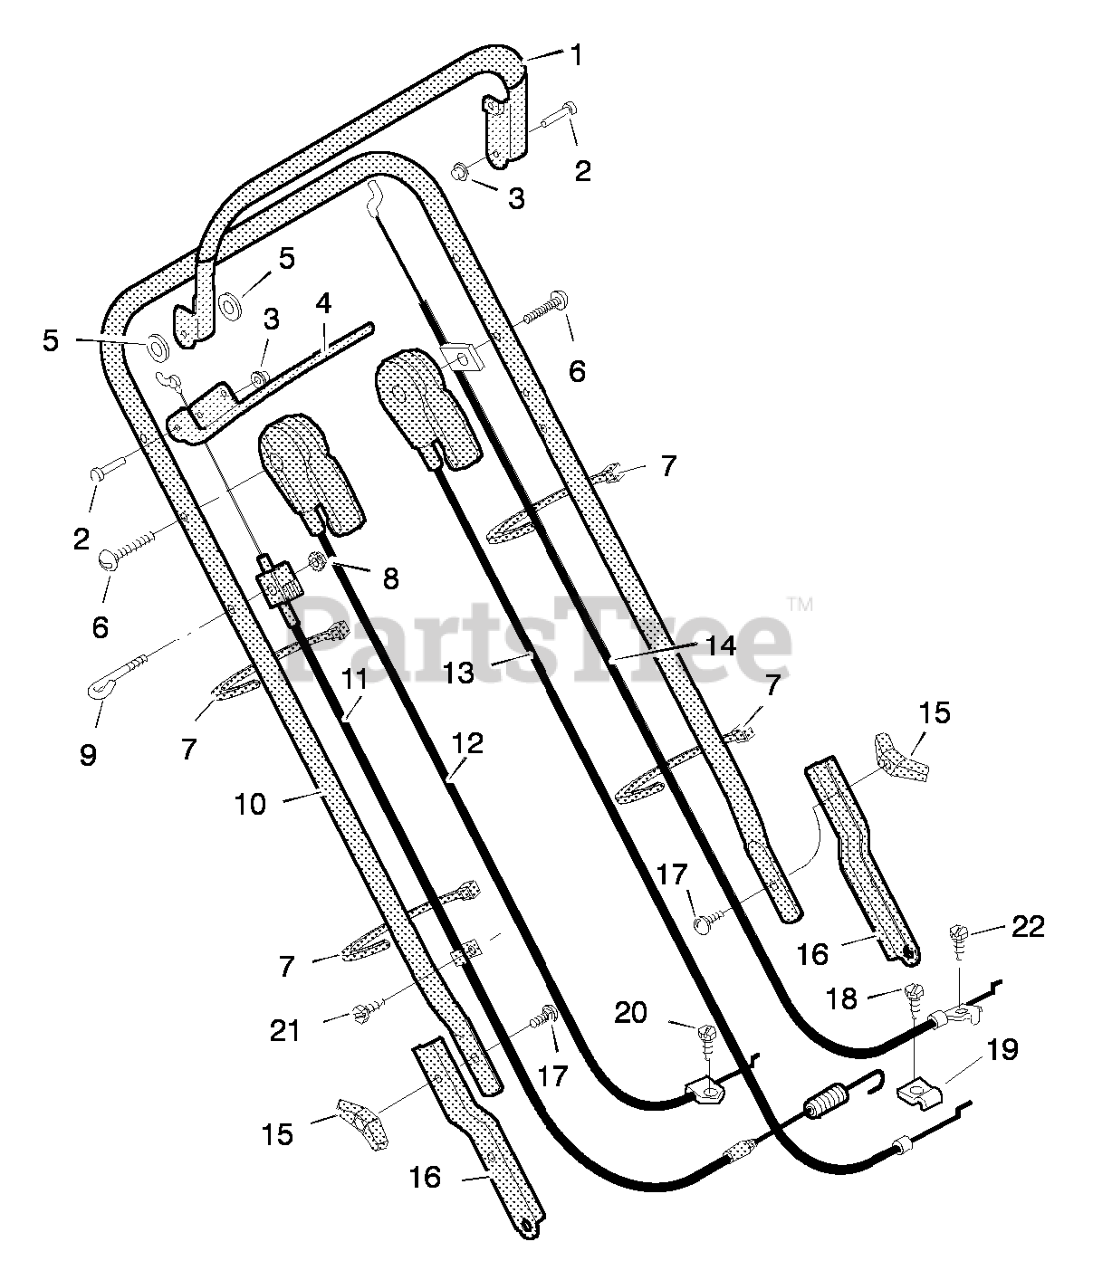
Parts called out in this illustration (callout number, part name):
1	Stop Lever
3	Push On Cap
4	Lever, Drive
7	Fastner, Cable
8	Locknut
9	Guide, Rope
11	Cable, Drive
12	Control, Speed
13	Throttle
14	Stop Cable
16	Bracket, Handle (Black)
17	Bolt, Carriage
18	Screw *
19	Bracket *
22	Screw *
